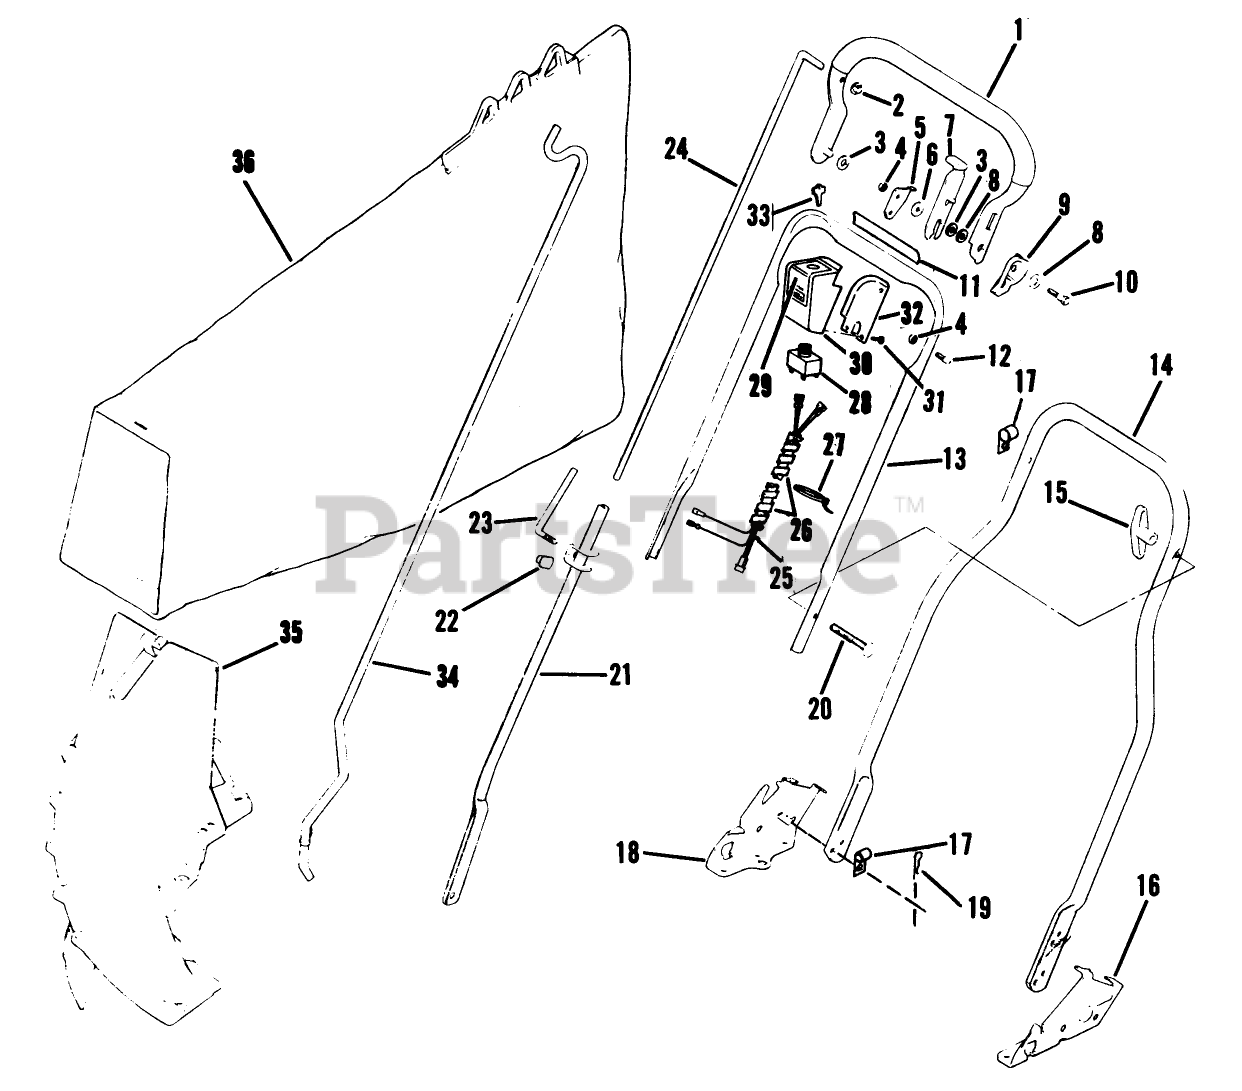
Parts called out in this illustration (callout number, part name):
3	WASHER M
4	LOCKNUT E
5	HANDLE STOP
6	WASHER
7	LEVER LOCKOUT
10	BOLT PIONEER
12	SCREW-HANDLE STOP
13	HANDLE
15	NUT-WING
18	HANDLE BRACKET
19	HAIR PIN
22	Nut
23	Screw
24	ROD CONTROL
30	HOUSING SWITCH
31	Screw
34	ROD GRASSBAG
36	ORDER 89814 W/G
